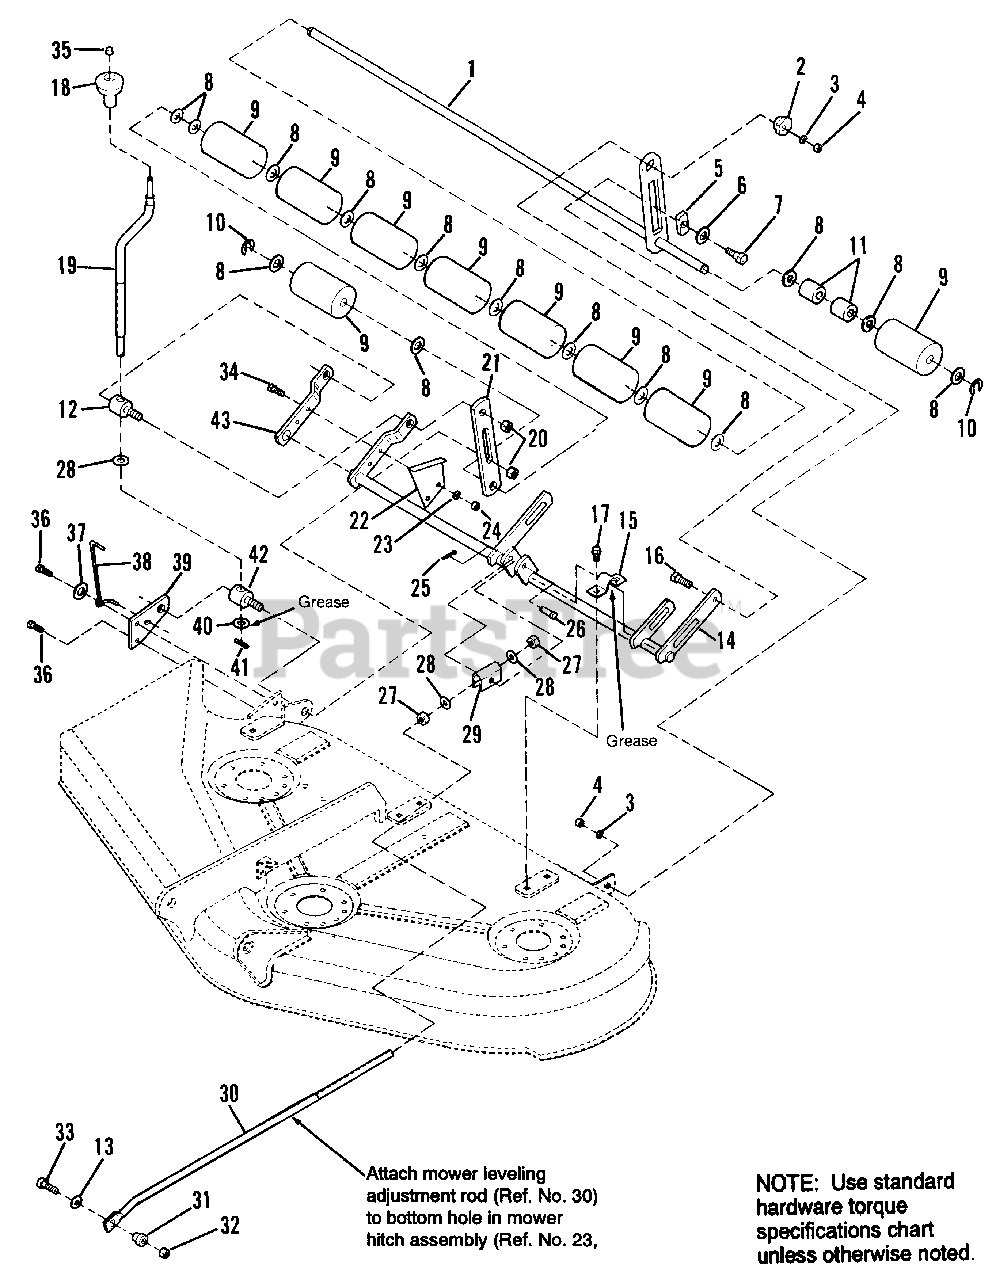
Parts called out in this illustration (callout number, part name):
1	SHAFT ASSY., Roller, 44" (Incl. Ref. Nos. 1, 10 & 11)
2	NUT, Hex Adjusting, .99 DIA .687
3	LOCKWASHER
4	NUT, Hex Hd., 3/8-16
6	WASHER, Plain,1/2
7	BOLT, Shoulder, 3/8-16 X 1.34
8	WASHER, 5/8
10	RING, Retaining
11	SPACER, .66 ID
12	TRUNNION, Threaded
13	WASHER, Plain
14	ARM ASSY., Mower
15	STRAP, Mower Arm Assy.
16	CARRIAGE BOLT, 3/8-16 x 1-1/2
17	SCREW, Hex Taptite, 5/16 x 3/4
18	KNOB, Height Crank
19	CRANK, Cutting Height
20	NUT, Hex, Flange Lock, 1/2-13
21	BAR, Roller
22	BRACKET, Cutting Height
23	LOCKWASHER, 5/16
24	NUT, Hex, 5/16-18
25	COTTER PIN
26	PIN, Clevis
27	NUT, Hex, Jam, 1/2-13
28	WASHER, 33/64
30	ROD, Adjustment
32	NUT, Hex, Whizlock, 3/8-16
33	CAPSCREW, Hex Head, 3/8-16 x 1-3/4
34	CAPSCREW, Hex Hd., 5/16-18 x 1-1/4
35	PALNUT
36	SCREW, Hex, Washer, Taptite, 5/16-18 x 1-1/4
37	WASHER, Flat, 5/16
38	INDICATOR, Cutting Height
39	PLATE, Mower Support
40	WASHER, Detent
41	PIN, Roll, 1" Long
43	ARM, Rear, Mower, R.H.
